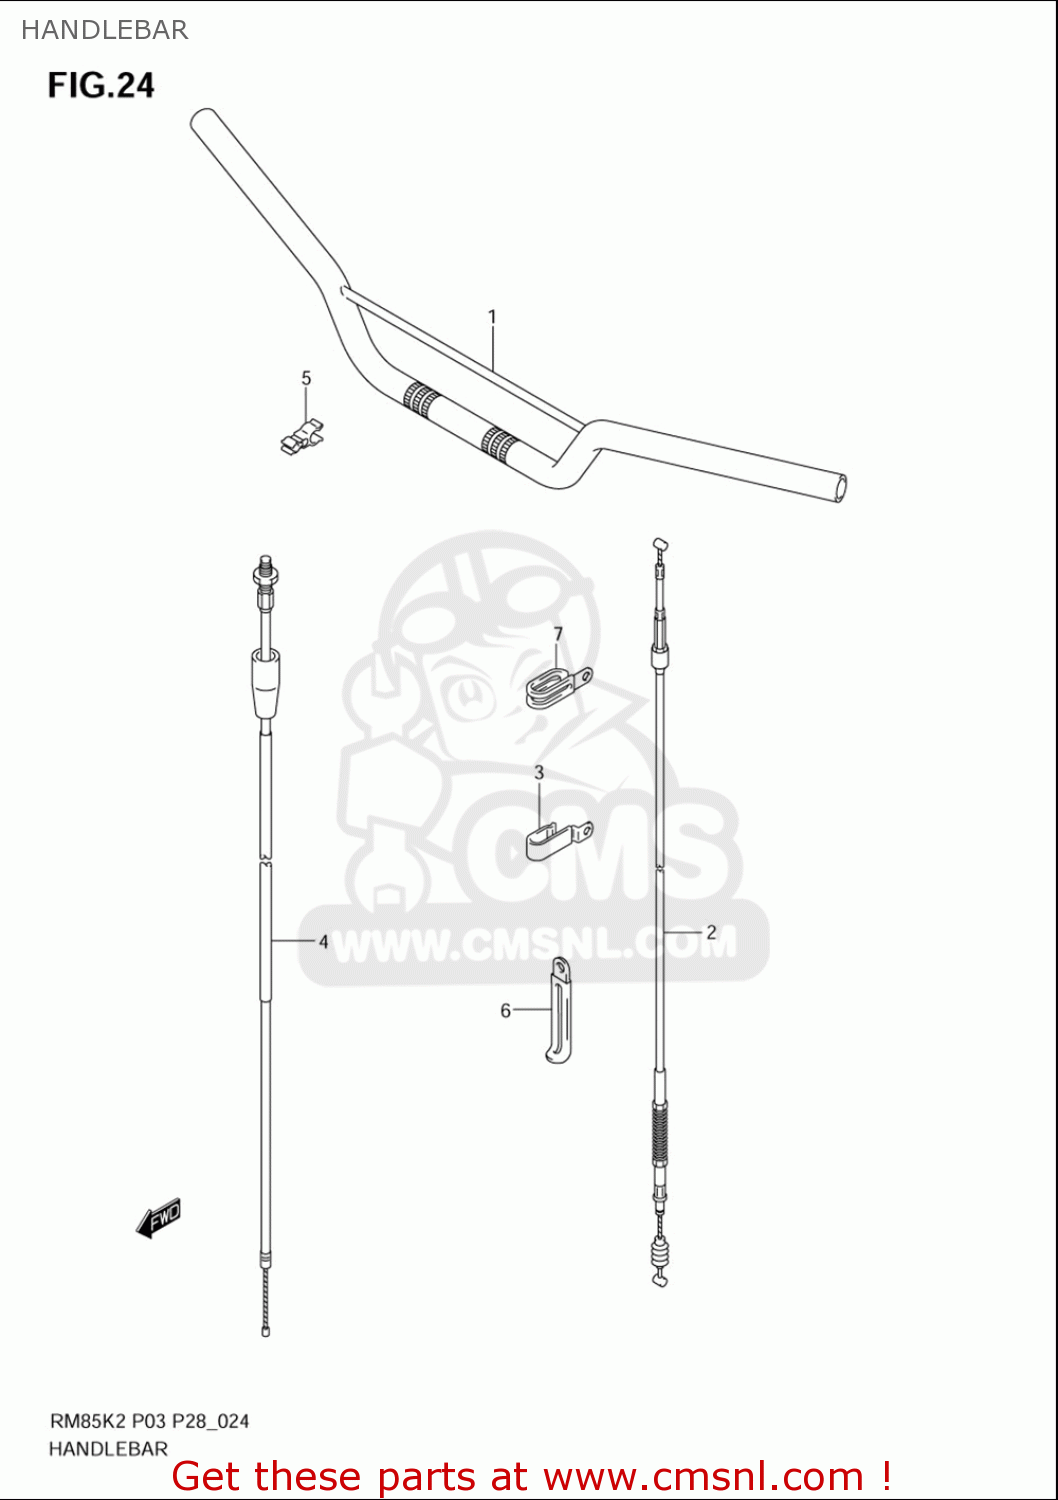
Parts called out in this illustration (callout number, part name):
1	HANDLEBAR COMP
2	CABLE ASSY,CLUTCH
3	CLAMP
4	CABLE ASSY,THROTTLE
5	CLAMP
6	CLAMP(L:65)
7	CLAMP
